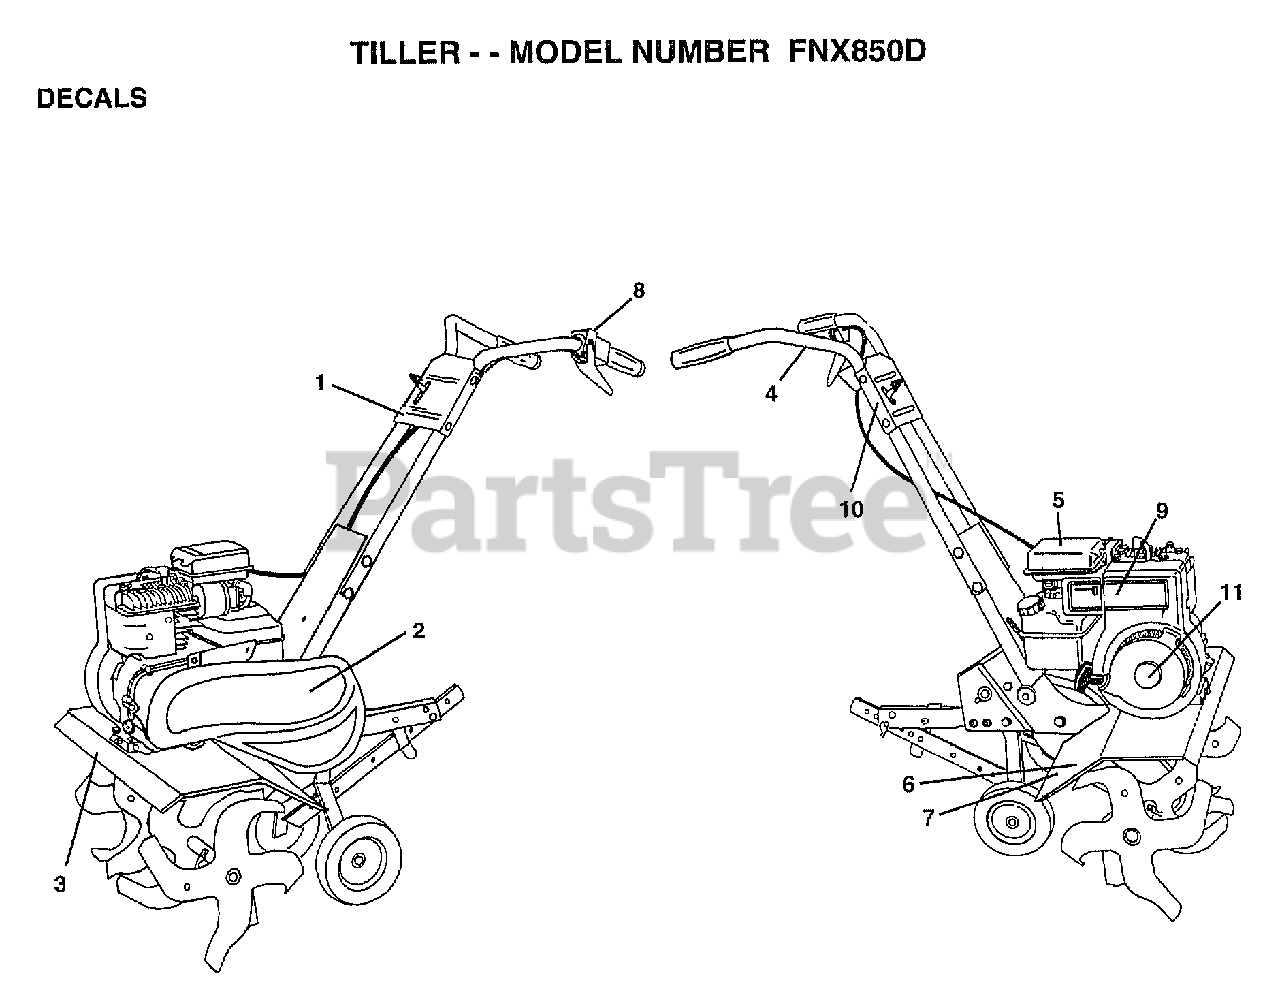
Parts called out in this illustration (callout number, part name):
1	DECAL HANDLE BRKT
3	DECAL TINE SHIELD
4	DECAL-PLACEMENT
5	DECAL TI
6	DECAL.EURO.ST.CE.
7	DECAL-WARNING
8	DECAL.CONTROL FOR
10	"DECAL CONTROL,PNL"
